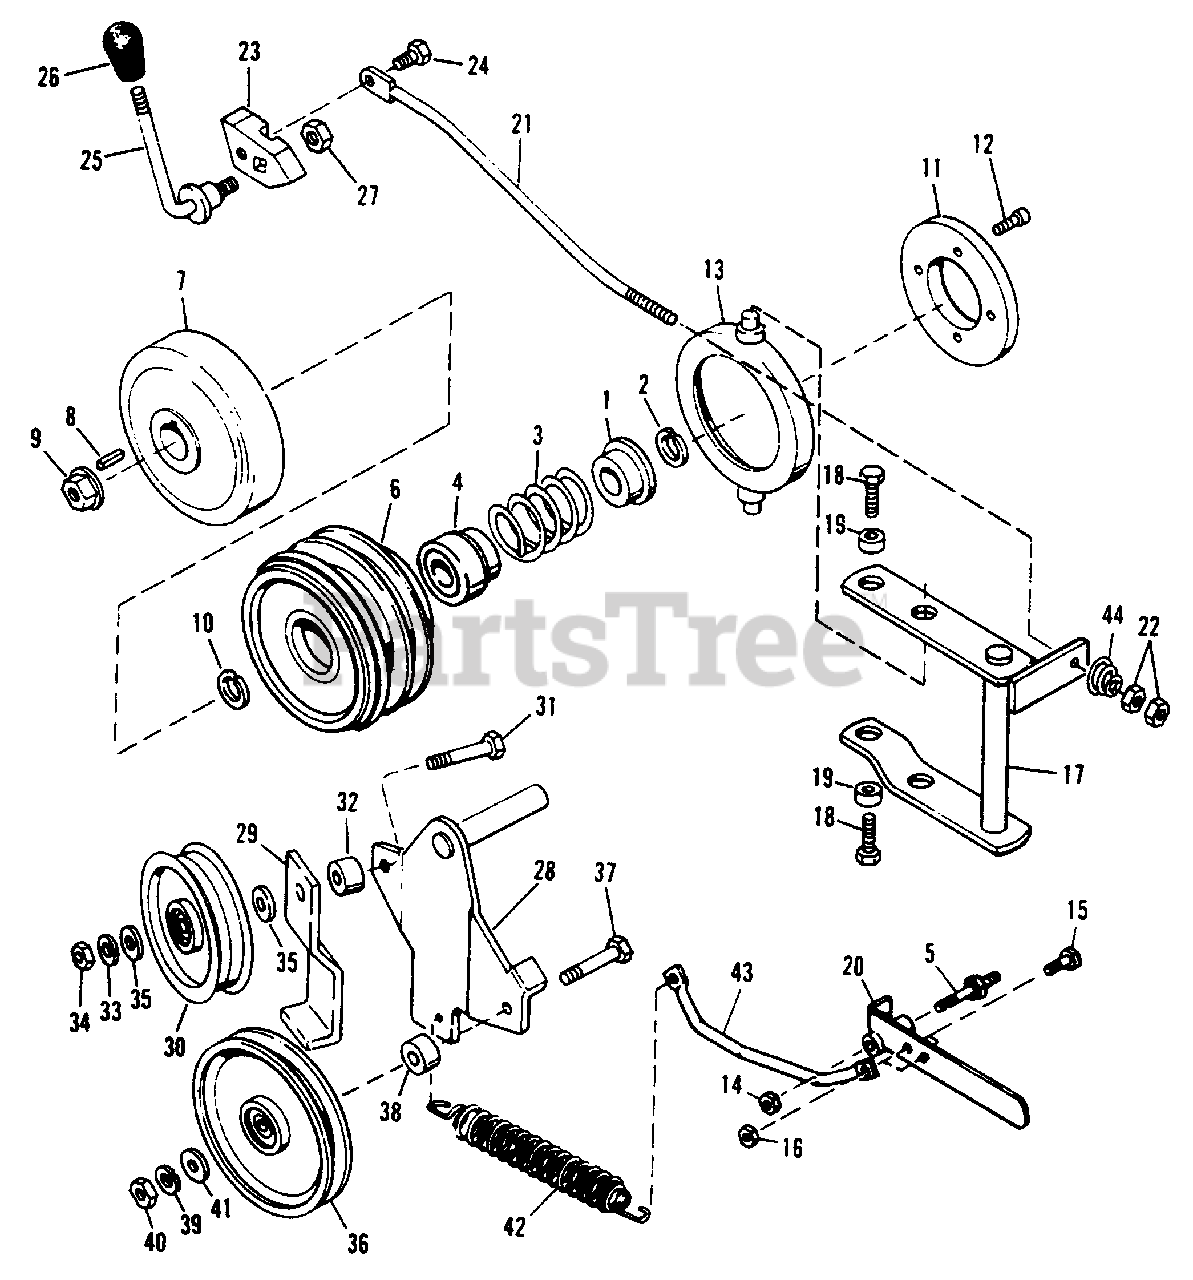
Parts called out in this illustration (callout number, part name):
1	Inner Spring Guide
2	Ring, Retaining
4	Bushing Assembly
7	Clutch Plate Assembly
9	Washer Base Lock Nut
10	Ring, Retaining
12	Socket Hd. Screw, 1/4"-20 x 5/8"
13	Support Brake Assembly
14	Full Hex Lock Nut, 7/16"-14
15	Hex Capscrew, 5/16"-18 x 3/4"
16	Full Hex Lock Nut, 5/16"-18
17	Pivot Assembly
18	Thread Forming Screw, 5/16"-18 x 3/4"
20	Handle Assembly
21	Control Rod
22	Full Hex Nut, 5/16"-18
24	Special Capscrew, 5/16" UNC-2A x 7/8" Grade 5
25	Handle, Clutch PTO
26	Knob
27	Full Hex Lock Nut, 3/8"-16
28	Pivot Arm Assembly
29	Belt Stop
31	Hex Capscrew, 3/8"-16 x 2"
33	Lockwasher, 3/8"
34	Full Hex Nut, 3/8"-16
35	Plain Washer, 5/16"
36	Idler Pulley
37	Hex Capscrew, 3/8"-16 x 2"
39	Lockwasher, 3/8"
40	Full Hex Nut, 3/8"-16
41	Plain Washer, 5/16"
42	Spring Tension
43	Spring Tension Rod
44	Conical Spring
